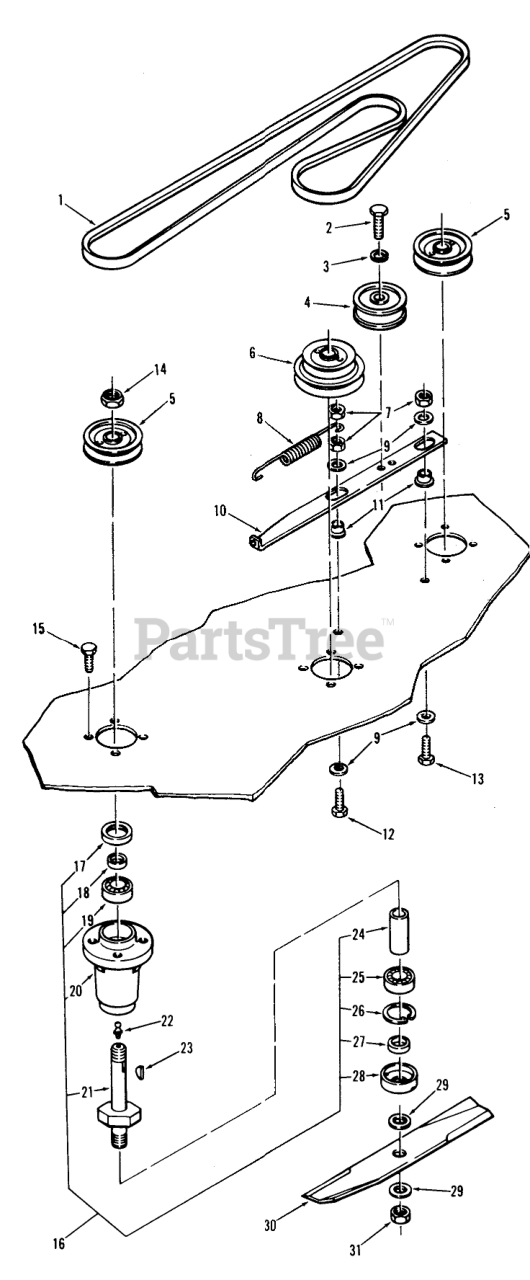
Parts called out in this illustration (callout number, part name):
1	V-BELT
1	V BELT
2	BOLT HEX SPECIAL
3	LOCKWASHER
4	Idler Pulley
5	PULLEY-BLADE DRIVE
6	PULLEY-48 MOWER SPDL
6	PULLEY-42 MOWER SPDL
7	Nut
8	SPRING-EXTENSION
9	WASHER
10	BAR-IDLER SUPPORT
11	Bushing/Spacer
12	Bolt
13	Bolt
14	Nut
15	Bolt
16	Spindle Assembly
18	SPACER-SEAL
19	BEARING-BALL
20	HOUSING-SPINDLE
21	Spindle Shaft
22	Zerk
23	Hi-Pro Key 3/16 x 5/8
24	SPACER
25	BEARING-BALL
26	Ring-Snap
27	SPACER-BLADE
28	CUP-SPINDLE
29	Washer
30	Blade
30	BLADE-14IN
31	Nut
45	ASM-SUPPORT,IDLER
